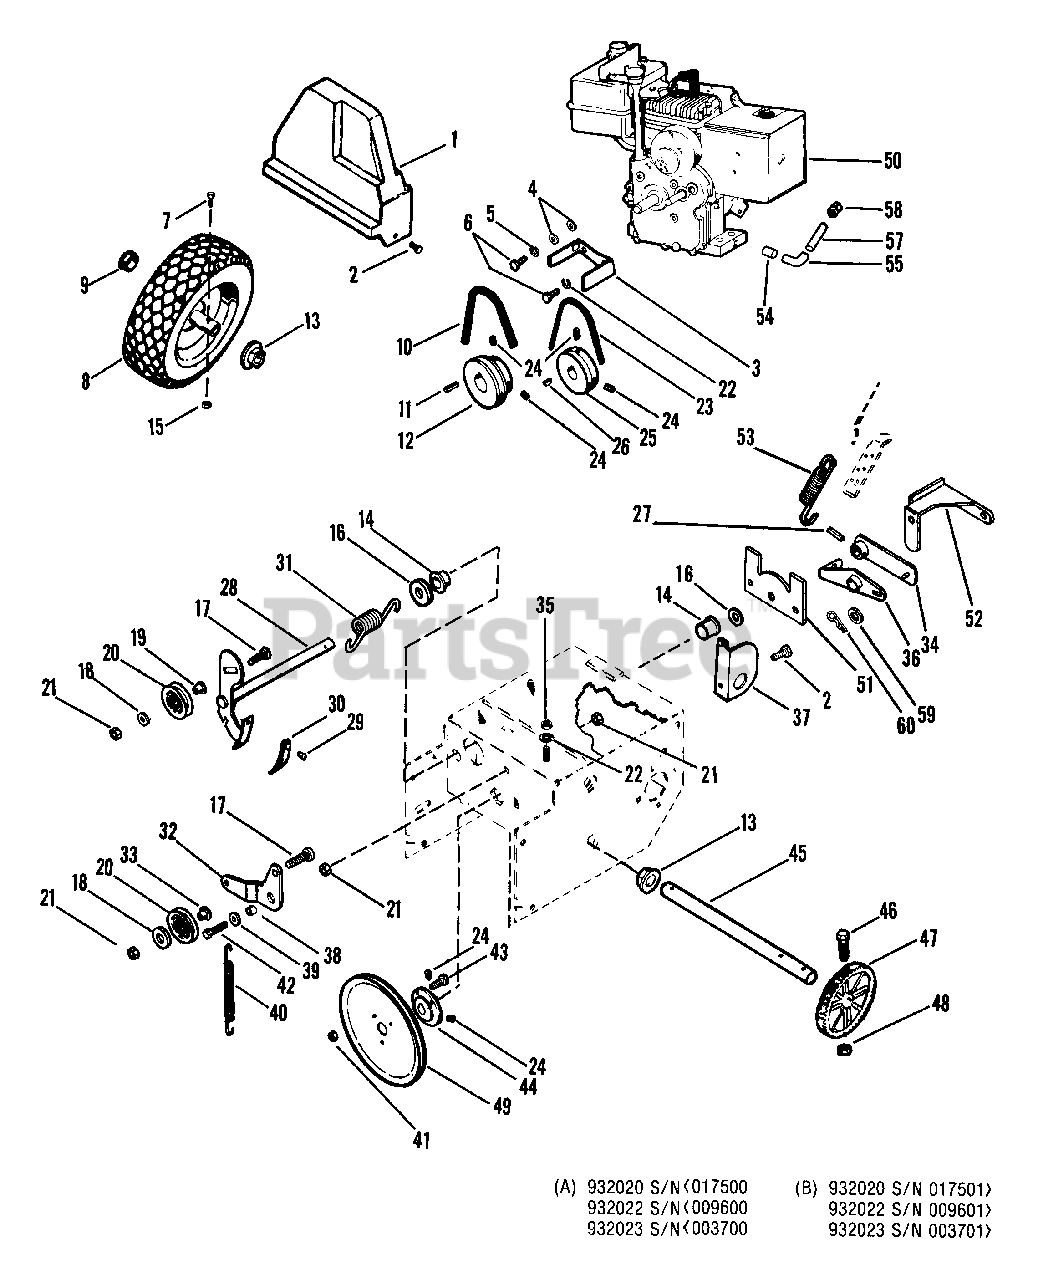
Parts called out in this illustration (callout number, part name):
1	BELT COVER
2	SCR-TAP .250-20X.37 HWH PL TR
3	BELT FINGER
4	WSHR-FL-STL .380X.875X.179 PL
5	WSHR-LK .313X.093 MED HICLR
6	BLT-HEX .31-24X.75 PL GR5
7	BLT-HEX .25-20X1.75 GR2
8	WHL
8	TUBE
8	TIRE 4.1/3.50X4
8	TIRE 4.10-4 NHS
8	T/WHL ASSY
8	WHL-COMP
8	T/WHL ASSY 4.10-4
8	RIM/HUB ASSY 4.10/3.50X6
8	TIRE
8	WHL-COMP 3.5 X 6
9	HOLE PLUG
10	V-BELT, 4L-COGGED
10	V-BELT, 4L-RAW EDGE
11	KEY-SQ .188X1.0X.188 SAE 8630
12	ENGINE SHEAVE
12	SHEAVE-ENGINE
13	BSHG-FLG .750X.873X.640X.900HX
14	BSHG-FLG.500X.625X.312X.750NY
15	NUT-LK TOP .250-20 PL
16	WSHR-FL-STL .531X1.062X.095 PL
17	BLT-RDHDSQNK .31-18X1.38SHT PL
18	WSHR-FL-STL .38X.875X.083 PL
19	SPCR, BRG .315X.50X.688X.281
20	IDLER
21	NUT-LK .312-18 GR A PL
22	WSHR-LK .312X.097 PL HVY
23	V-BELT, 3L-COGGED
24	SCR-SET .32-18X.38 SKHCUPNL OH
25	SHEAVE CAMSHAFT
25	SHEAVE-CAMSHAFT
26	KEY-WDRF .125X.625X.250 SAE5
27	PIN-ROLL .156X.88
28	BRAKE CLUTCH ARM W/LINING
29	RVT-TBLR .187X.437 RH ST PL
30	BRAKE LINING
31	SG-TORS .148X1.0X1.53
32	IDLER ARM
33	BSHG, FLG .325X.499X.26X.88
34	LEVER CLUTCH
34	LEVER WELDMENT
35	NUT-HEX .312-18
36	LEVER
36	SPRING LEVER WELDMENT
37	CLUTCH BRACKET GUARD
38	SPACER BUSHING .5 X .32 X .163
39	WSHR-FL-STL .344X1.375X.075 PL
40	SG-TENS .047X.44X3.37 WLD 1.47
41	NUT-FLG. .312-18 PL
42	BLT-HEX .31-18X.63 PL GR 2
43	BLT-SERRDHD SL .31-18X.75 YZ
45	AXLE SHAFT
46	BLT-HEX .25-20X1.75 GR 8
48	NUT-LK TOP .250-20 PL
49	PLY-V 8.0 X 1.25 3BLT SALEM
50	2.7 HP LAUSON ENGINE
50	3.5 HP LAUSON ENGINE
50	5.0 HP LAUSON ENGINE
50	3.5 HP LAUSON ENGINE W/PTO
50	5.0 HP LAUSON ENGINE W/PTO
50	3.5HP TEC ENGINE
50	5.0HP TEC ENGINE
50	ENGINE-HSSK 50 TEC W/PTO
50	ENGINE-4 HP TEC W/PTO
50	ENGINE-HSSK 40 TEC
50	ENGINE-7 HP TEC W/PTO
51	COVER
52	BELLCRANK
53	SG-TENS .135X.69X5.75 WLD 150
54	NIPPLE
55	STREET ELBOW
55	ELBOW 90 1/4-18 NPTF
57	NIPPLE
58	HEX CAP
59	WSHR-FL-STL .268X.562X.046 PL
60	PIN-HAIR INT .08X.18X1.18
